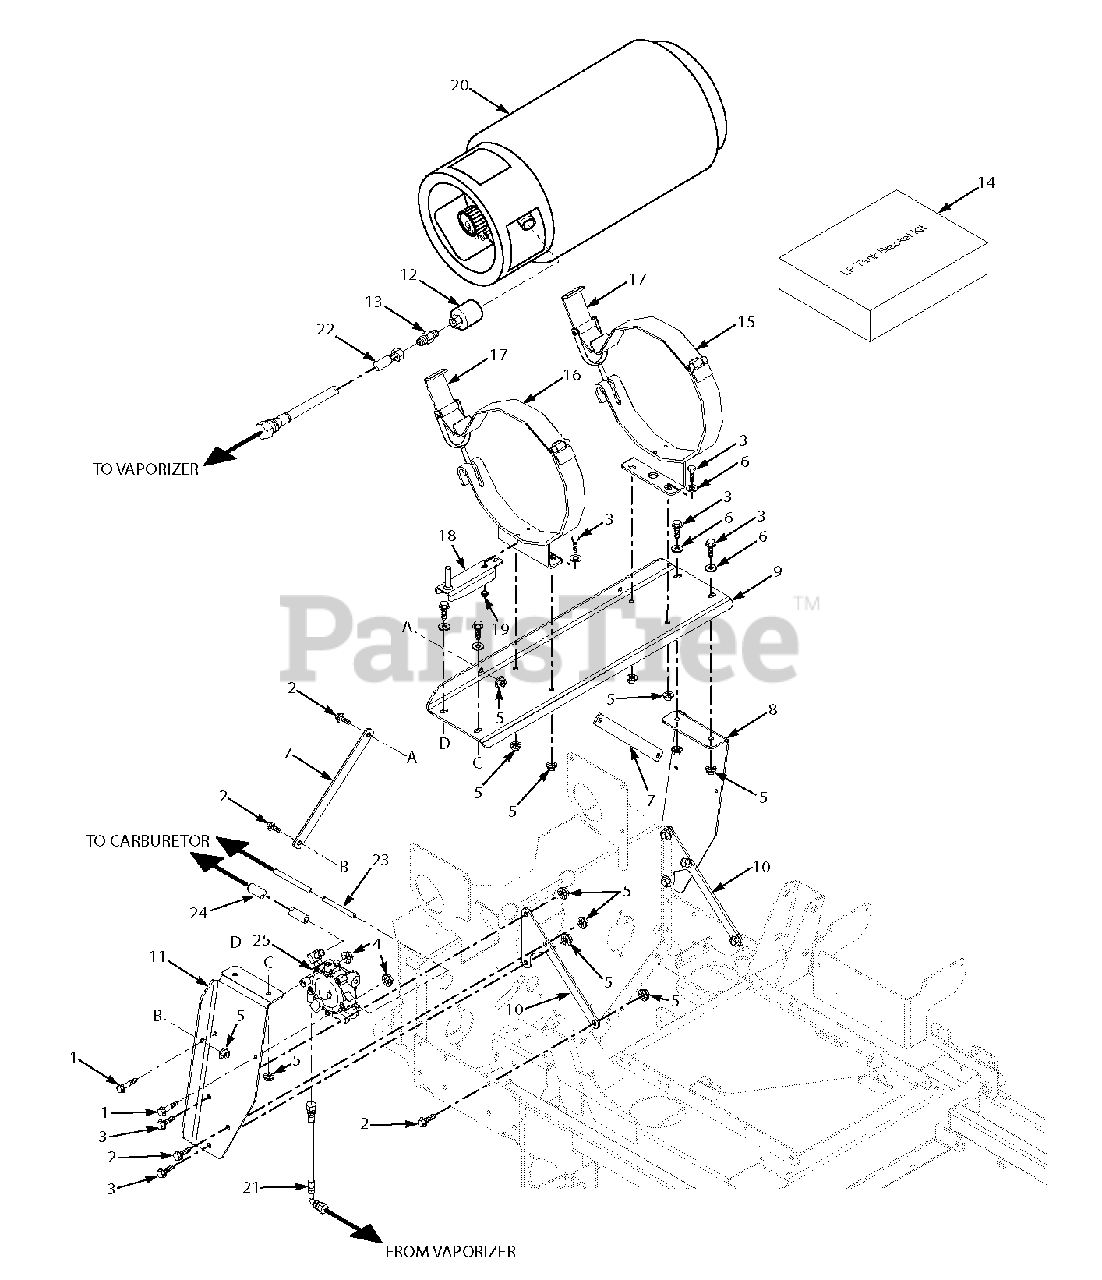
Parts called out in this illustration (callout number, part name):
1	Bolt, Heax Head 5/16-18 x 1-3/4"
2	Bolt, Head Head 3/8-16 x 3/4"
3	Bolt, Hex Head 3/8-16 x 1"
4	Nut, Serrated Flange 5/16-18
5	Nut, Serrated Flange 3/8-16
6	Flatwasher, 3/8-.391 x .938 x .105
7	Brace
8	Mounting Bracket, Tank Support LH
9	Support, LP Tank
10	Brace, LP Tank Mounting Bracket
11	Mounting Bracket, Tank Support RH
12	LP Quick Coupler
13	Adapter Fitting, 9/16-18 SAE x 1/4" Pipe
14	Mounting Bracket Kit
15	Mounting Bracket, LP Tank Front
16	Mounting Bracket, LP Tank Rear
17	Handle, LP Tank Mounting Bracket
18	Bracket, LP Tank Locator
19	Bolt, Hex Head 1/4-20 x 3/8" Locking
20	LP Tank
21	LP Fuel Line, 10"
22	LP Fuel Line, 32"
23	Hose
24	Hose
25	LP Regulator
